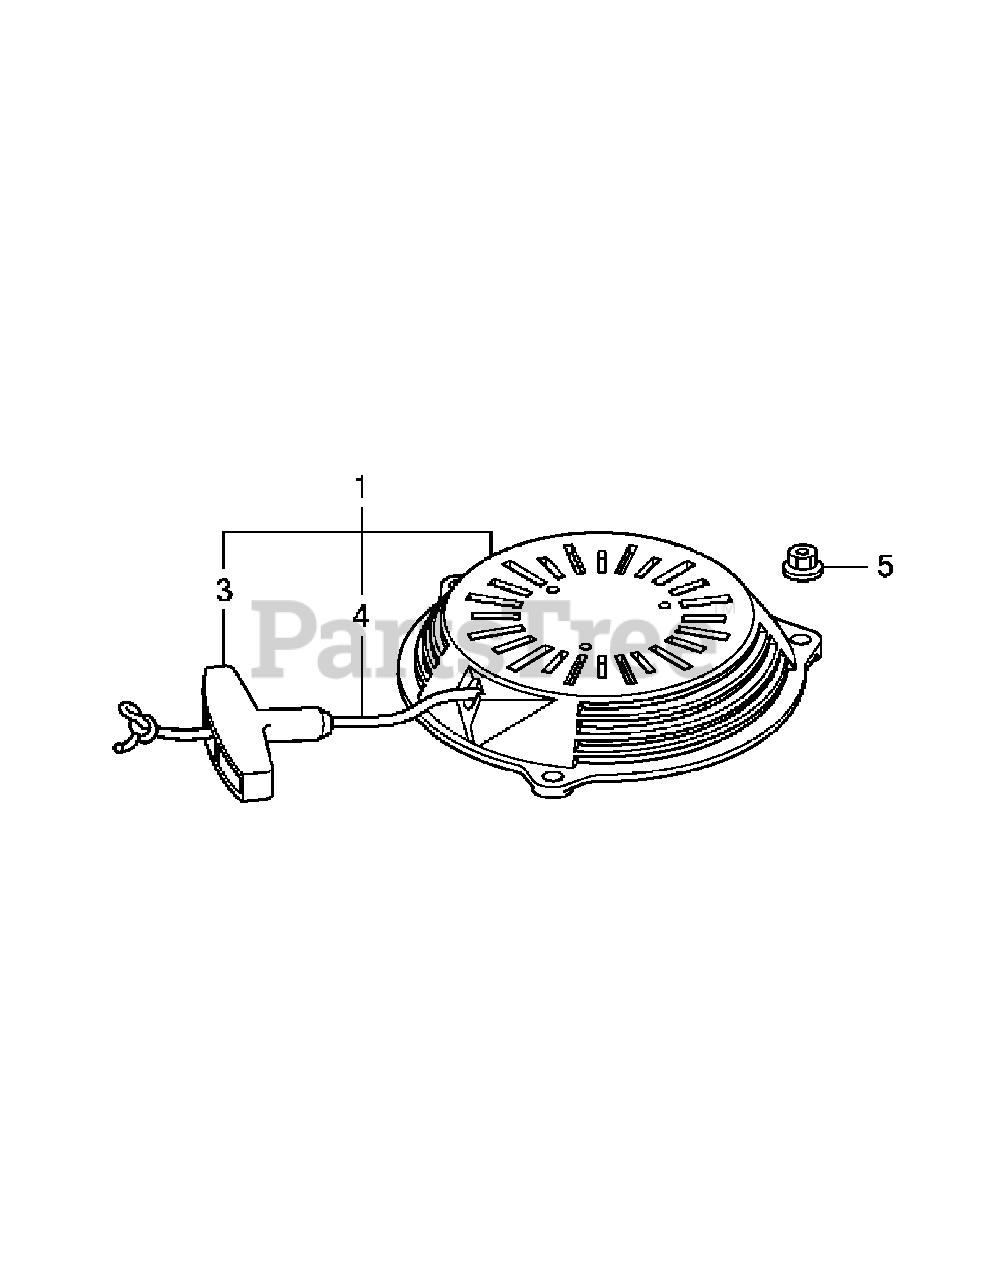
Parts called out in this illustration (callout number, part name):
1	Pri; Starter Assy., Recoil 'nh1'
3	Grip, Starter.
4	Rope, Recoil Starter.
5	Nut, Flange (6mm).
